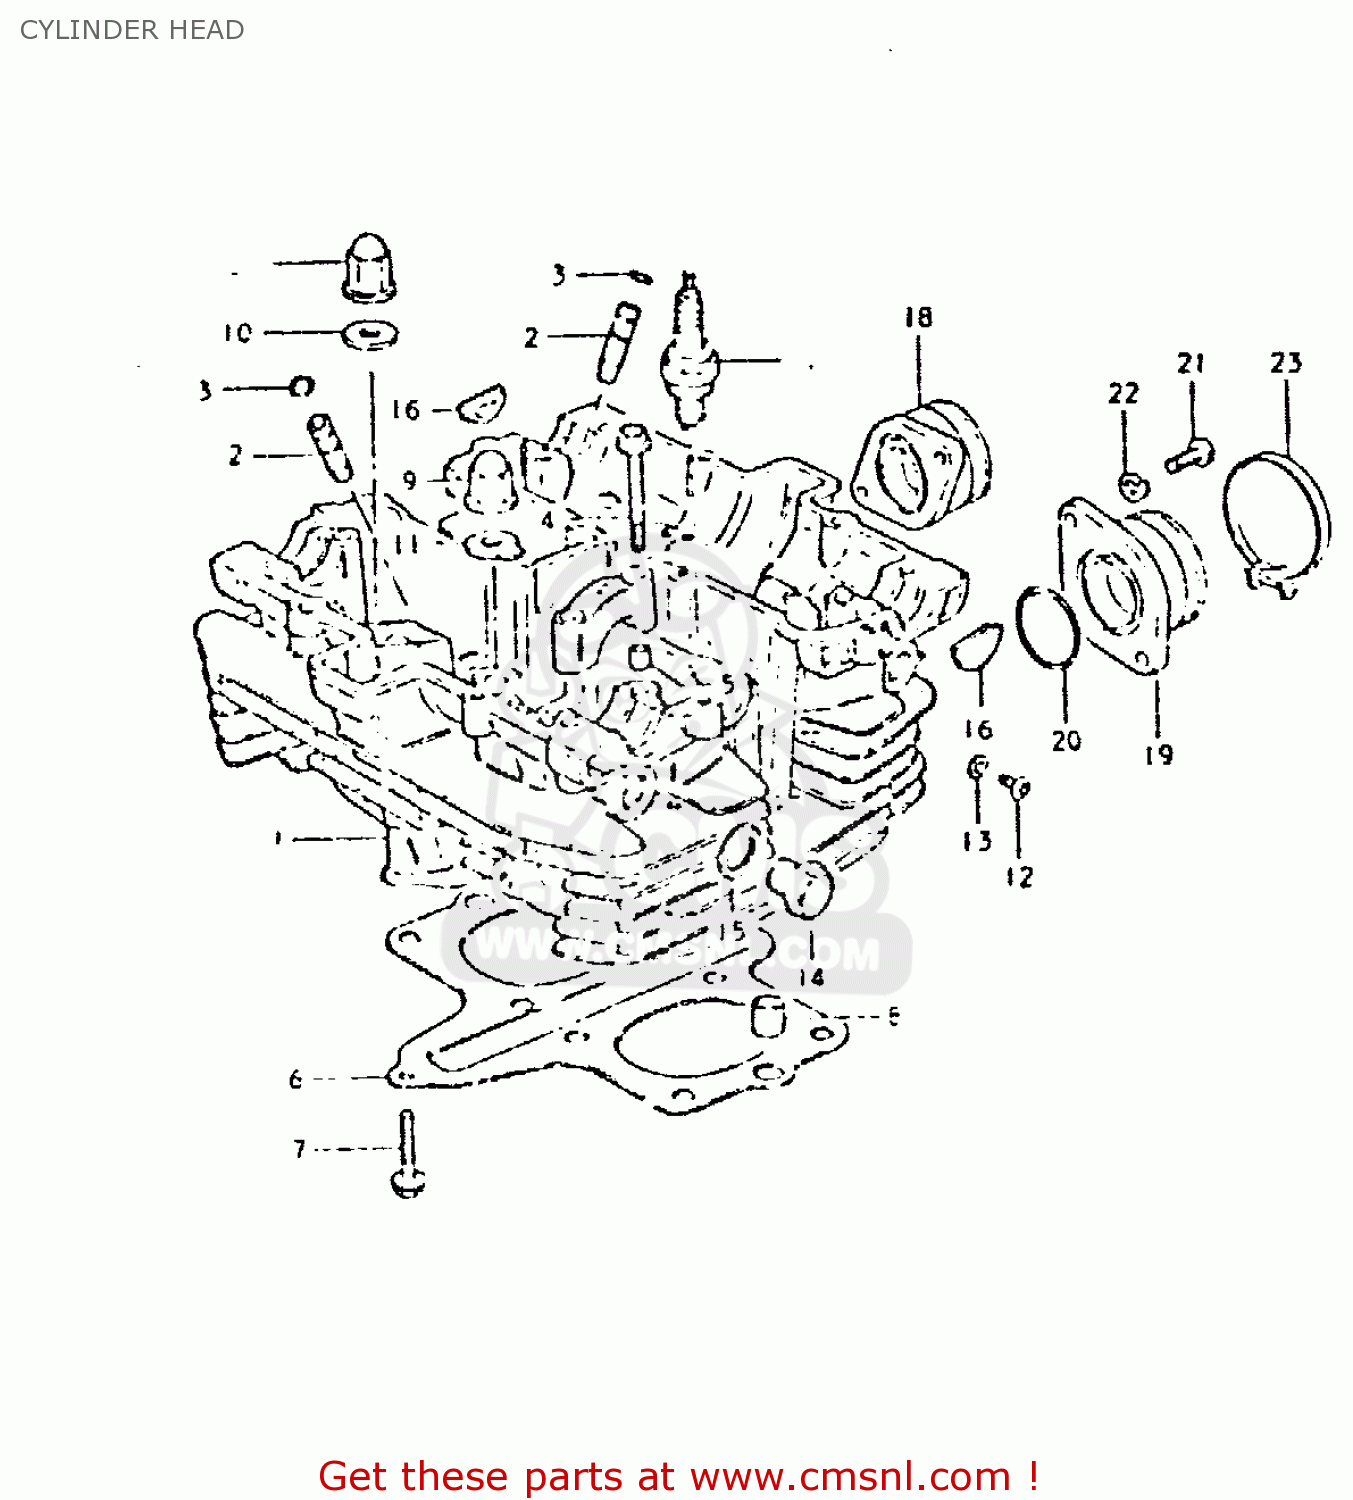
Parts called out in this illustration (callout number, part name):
1	CYLINDER HEAD SET
2	GUIDE,INTAKE VALVE
3	RING,SNAP
4	BOLT(6X39)
5	PIN(6.2X8X11)
6	GASKET (MCA)
7	BOLT
8	PIN
9	NUT
10	GASKET (NAS)
11	GASKET(10X22X2.3) (NAS)
12	SCREW
13	GASKET(5.3X9.3X1.2) (NAS)
14	PLUG (14X12)
15	GASKET(14X19.2X2) (NAS)
16	PLUG
17	SPARK PLUG DR8ES-L
18	PIPE,INTAKE,R
19	PIPE,INTAKE,L
20	O-RING
21	SCREW
22	LOCK WASHER
23	CLAMP
